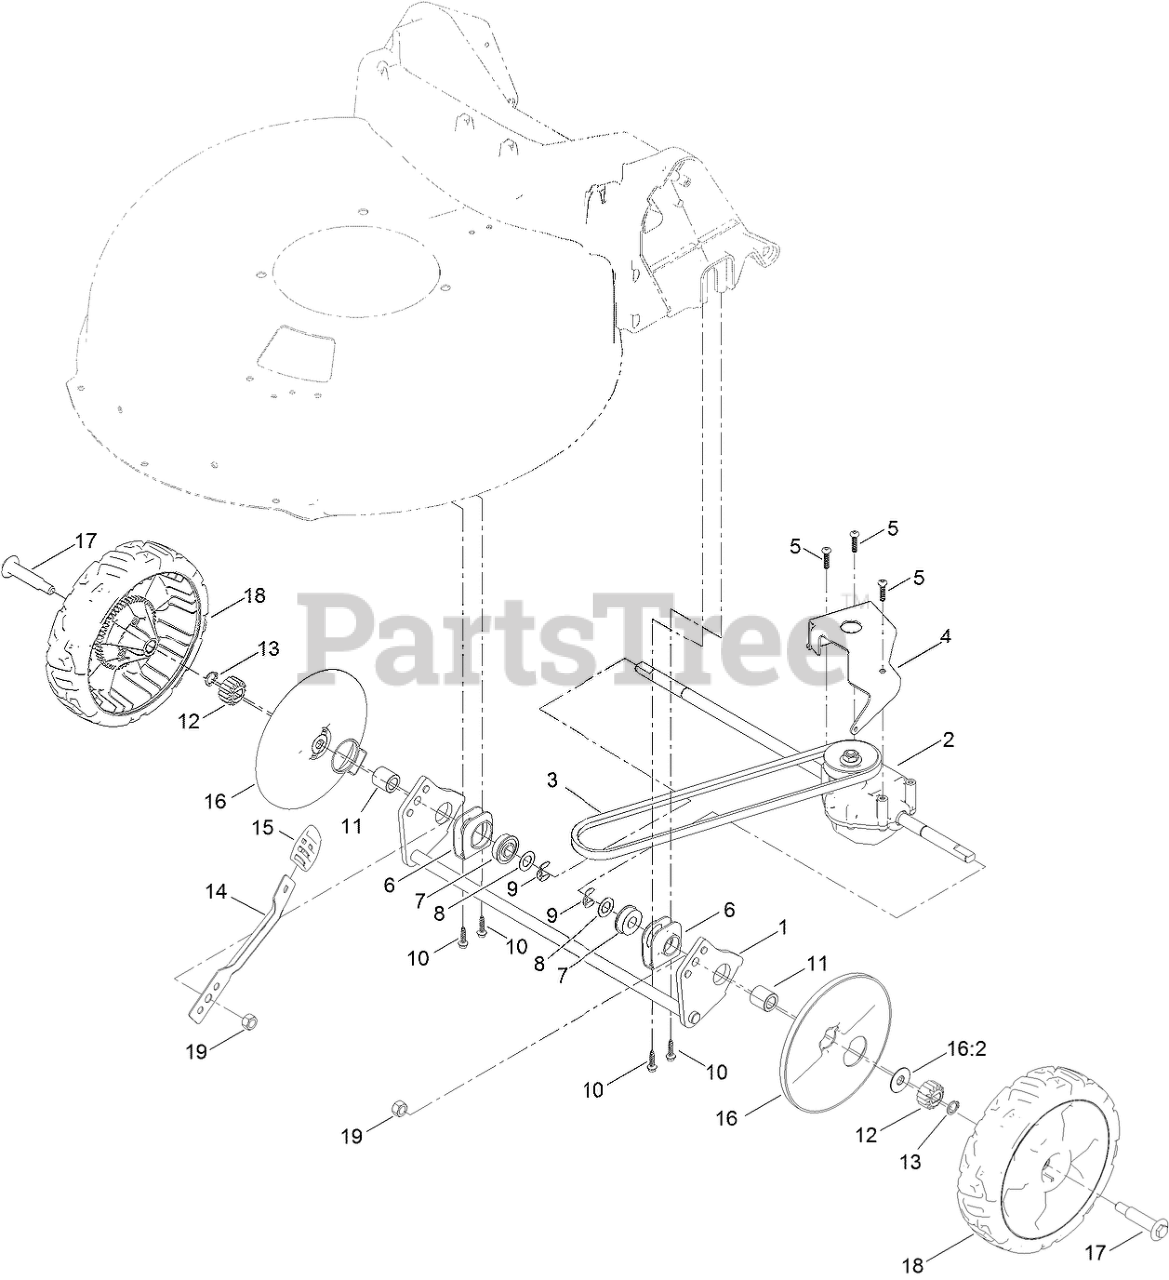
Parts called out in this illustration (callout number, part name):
1	AXLE-REAR
2	TRANSMISSION
3	V-BELT
4	BRACKET-TRANSMISSION
5	SCREW-PLASTITE
6	RETAINER-BEARING
7	BEARING-BALL
8	WASHER-PLAIN
9	RING-RETAINING,CLIP
10	SCREW-HWH
11	BUSHING-SLEEVE
12	GEAR-PINION, 15T
13	RING-RETAINING
14	ARM-SPRING
15	KNOB-LEVER, HOC
16	WHEEL COVER ASM
16:2	WASHER-STEPPED
17	BOLT-SHOULDER
18	WHEEL GEAR ASM, 8IN
19	NUT-HEX
